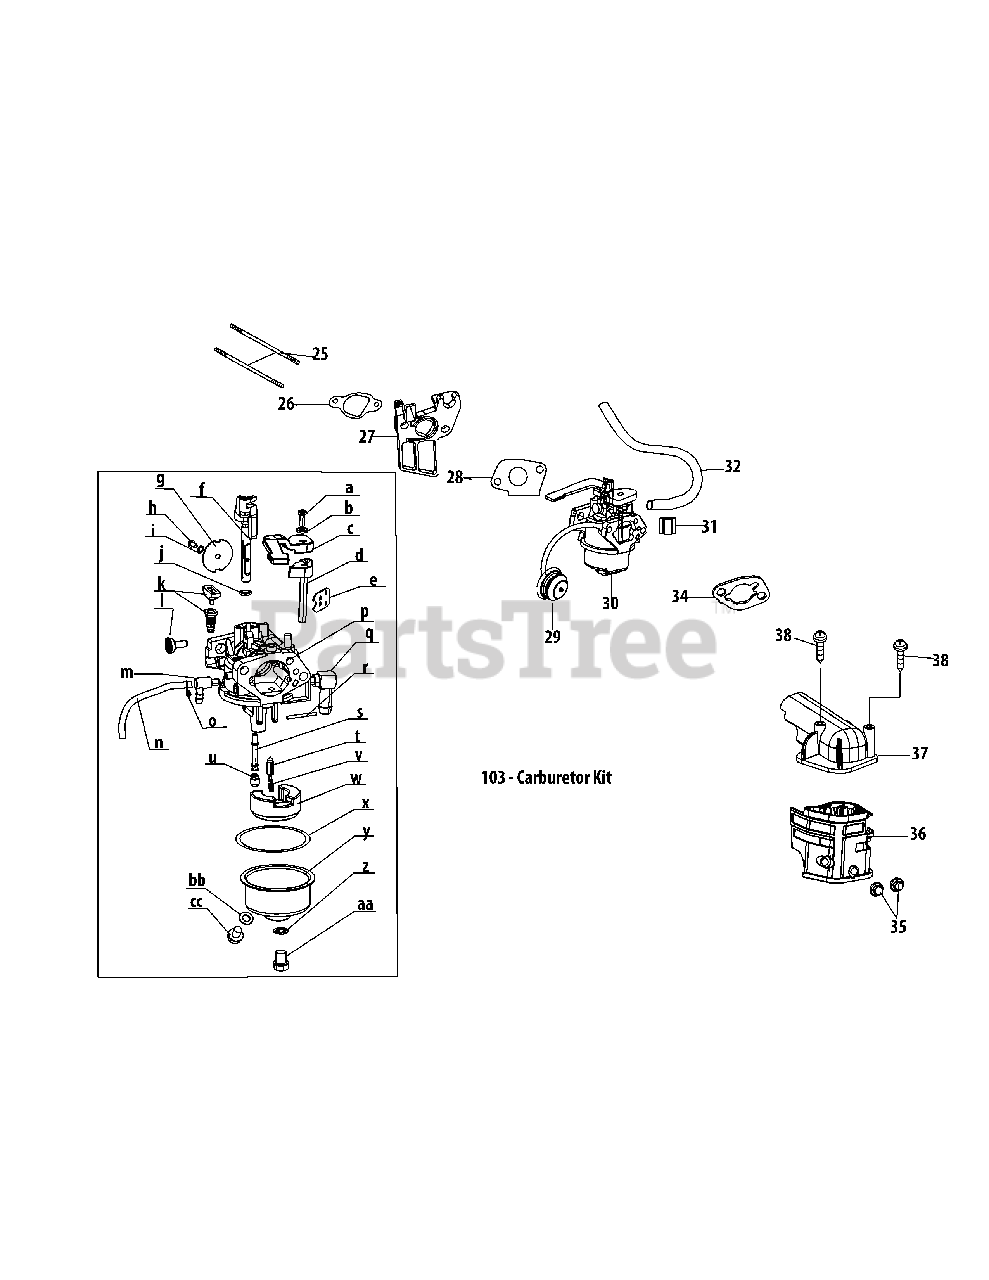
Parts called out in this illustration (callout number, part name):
25	Stud, M6×113, Intake
26	Gasket, Port, Intake
27	Insulator, Carburator
28	Carburetor Gasket
29	Primer Assembly
29	Primer Bulb
30	Carburetor Assembly
31	Fuel Hose Clamp
32	Fuel Hose
34	Carburetor Gasket Plate
35	Nut M6
36	Air Cleaner Housing
37	Air Cleaner Assembly
38	Self-Tapping Bolt M4.2×45
103	Carburetor Kit
